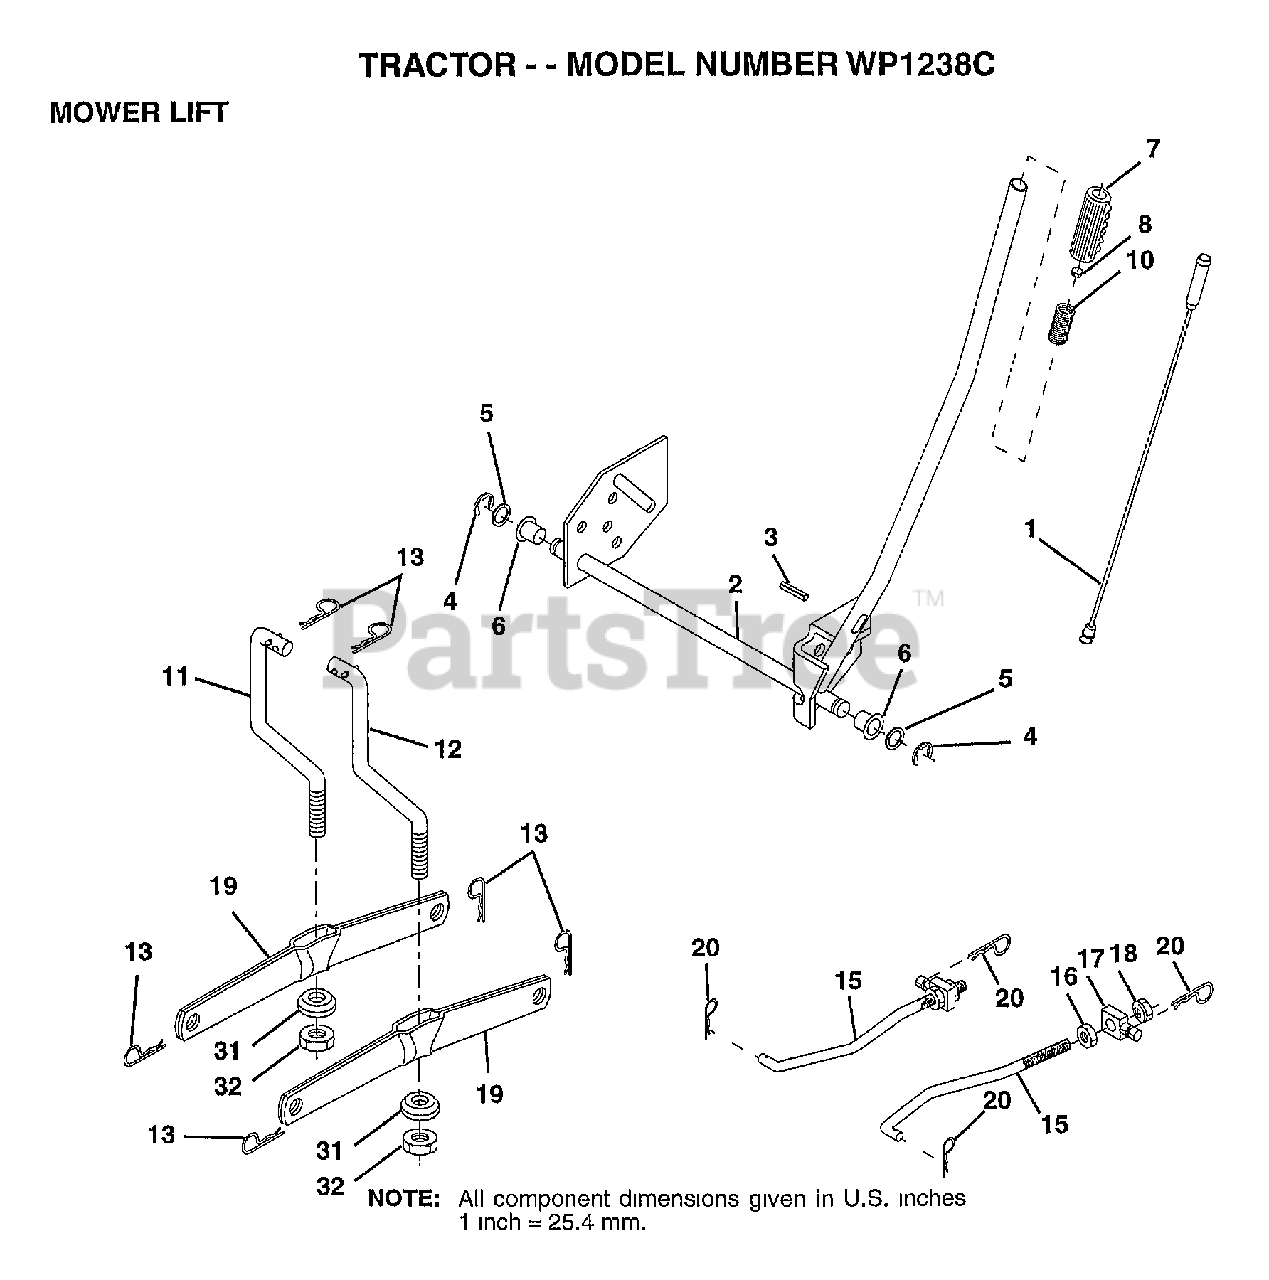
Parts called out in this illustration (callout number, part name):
1	WIRE ASM
3	PIN-GROOVE LT
5	WASHER
6	NYLON BEARING
7	GRIP
15	LINK.FRONT
16	NUT
17	TRUNION
18	NUT.LK.W/WSH.1/2.
19	ARM SUSP REAR
20	RETAINER.SPRING
31	BEARING PVT LH
32	NUT.CROWNLOCK.3/8
